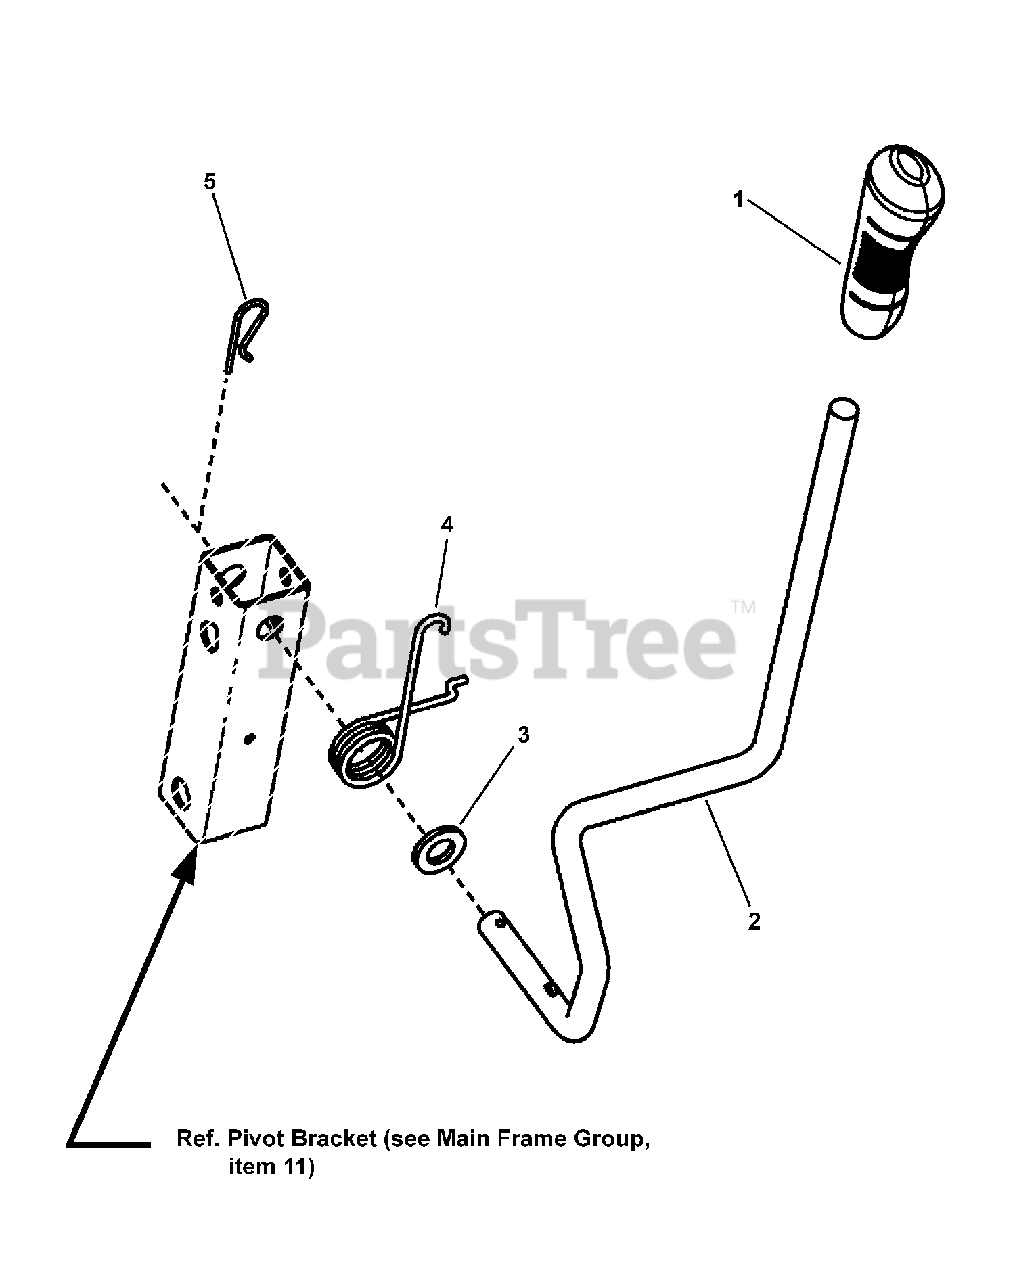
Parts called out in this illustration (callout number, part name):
1	GRIP, Handle
2	HANDLE, Lift
3	WASHER, .550 ID x 1" OD Flat
4	SPRING, Torsion
5	HAIR PIN, .092 Dia.
